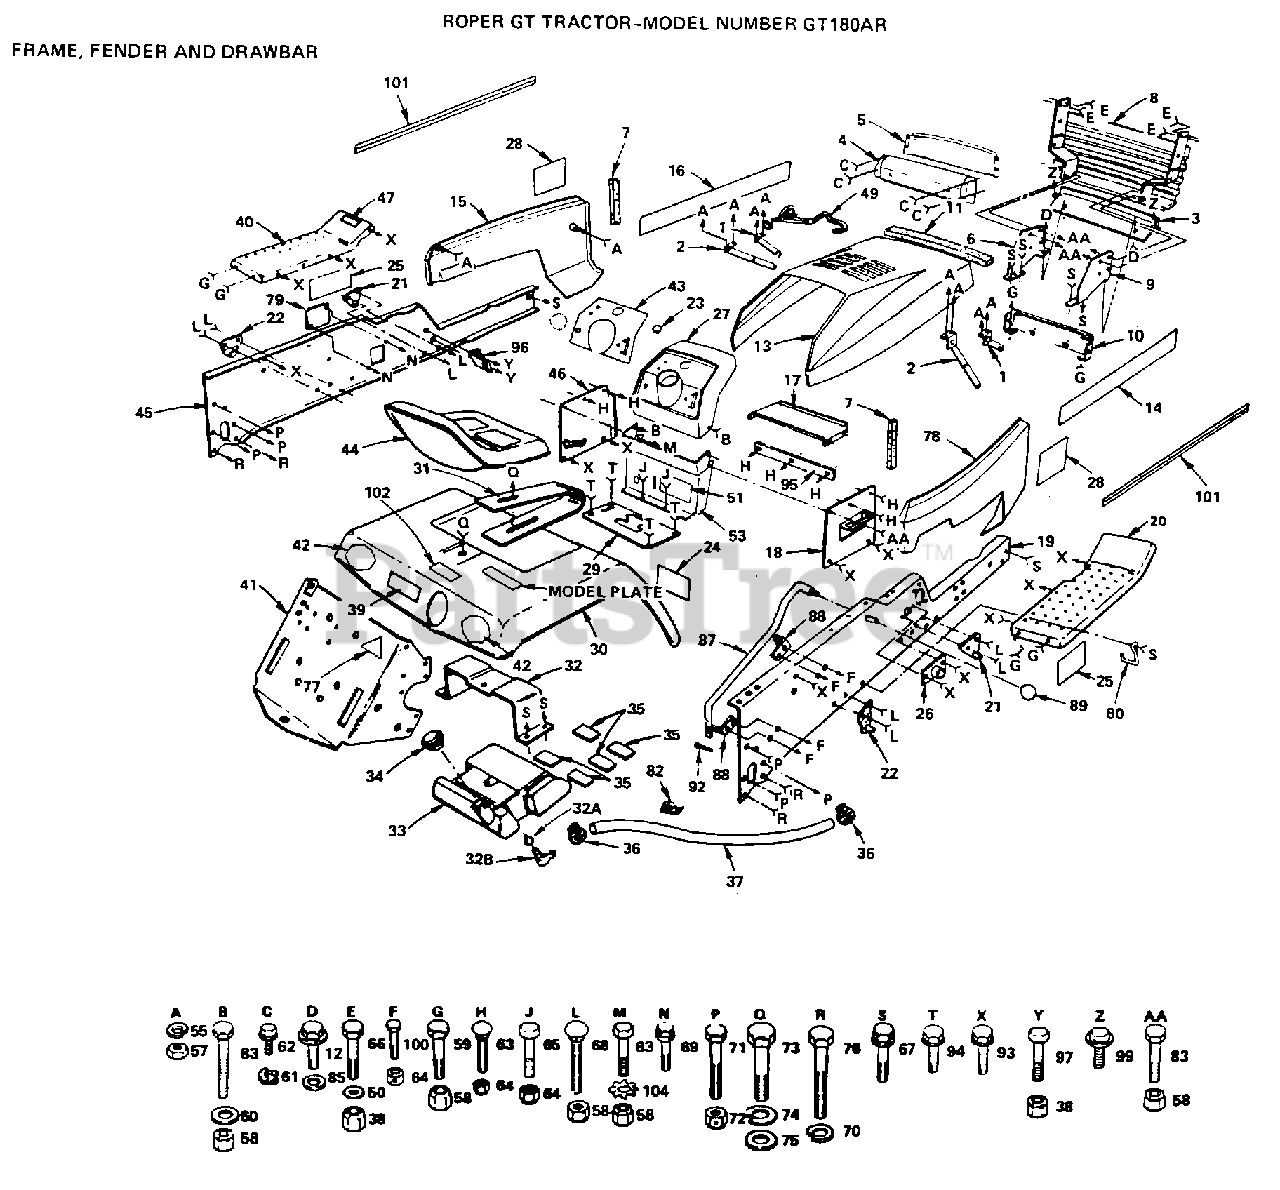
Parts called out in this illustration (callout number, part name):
6	SUPPORT-GRILL
7	FOAM STRIP HYT
9	SUPPORT-GRILL
11	FOAM-STRIP LT
12	SCREW
21	BRACKET ASSY
22	BRACKET ASSY
23	PLUG-DASH T
24	DECAL-CAUTION
32A	SPROCKET, 9 TEETH
32B	FUEL TANK STEM GT
35	PAD-SPACER T
39	DECAL-CAUTION
51	DECAL, INSTRUCTION
53	DASH ASSEMBLY
60	WASHER
61	"""J"" FASTENER LT"
63	BOLT
66	BOLT T
67	SCREW
68	BOLT
69	SCREW
70	LOCKWASHER
71	BOLT
72	NUT GTV
73	BOLT
75	WASHER
82	CLIP T
83	BOLT
85	WASHER M
87	ROD SHIFT GTV
93	SCREW LT
96	BRKT SWITCH GT
97	BOLT LT
99	SCREW HEX CRT
100	BOLT
104	LOCKWASHER
